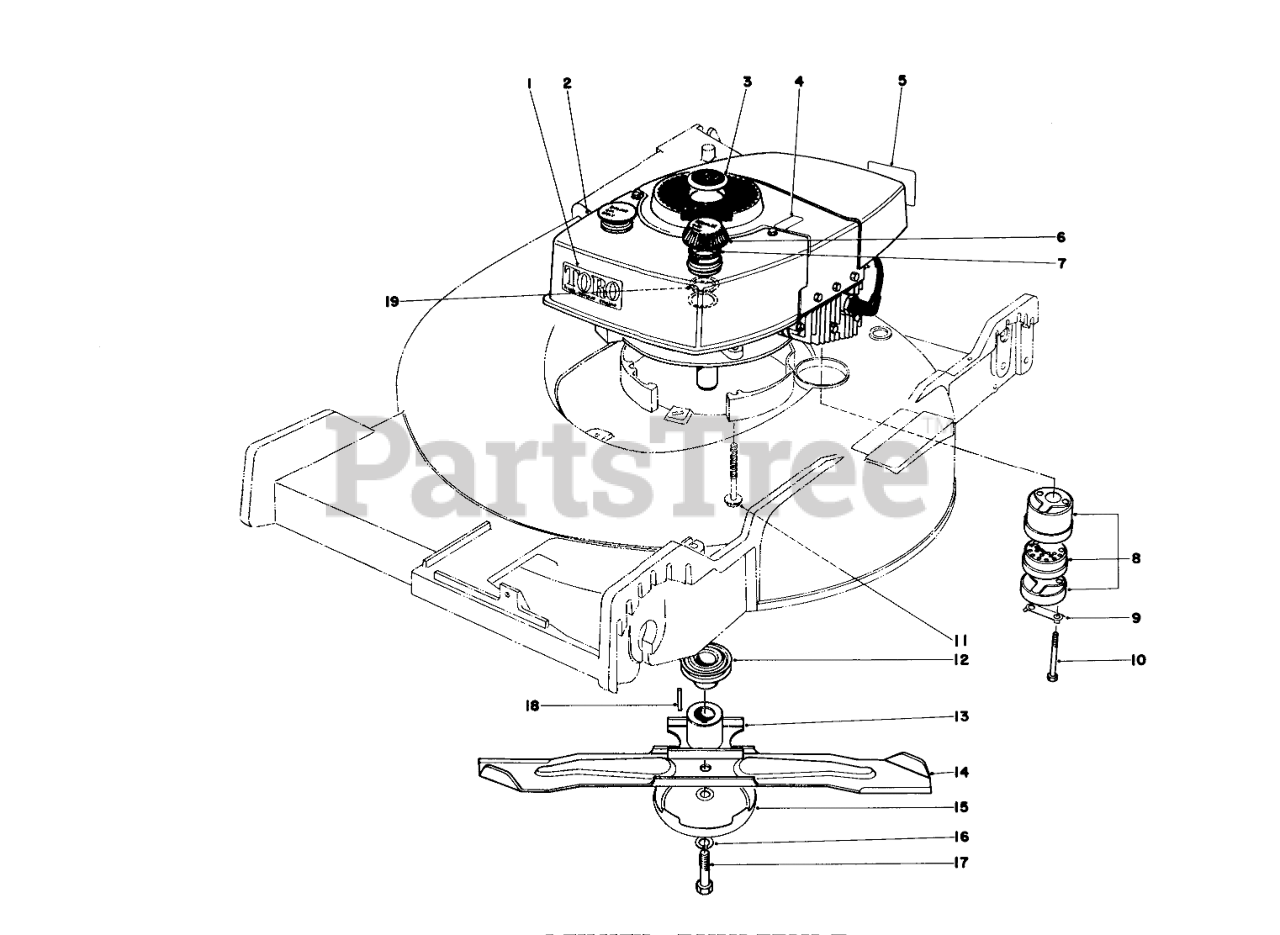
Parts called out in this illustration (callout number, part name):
1	High Torque
2	Engine
3	PLUG BUTTON
4	Decal Lockout
5	Decal Maintenance
6	Gas Cap Assembly (Incl. Ref. #7 & 19)
7	GASKET
8	Muffler Assembly (Incl . Ref. #9 & 10)
9	CLIP - LOCKING
10	SCREW-HH
11	3/8-16 X 2-3/4 CAPSCR
12	DRIVER PULLEY
13	Blade Retainer
14	Blade
15	AntiScalp Cup
16	WASHER-LOCK
17	SCREW-BLADE
18	Key Square
19	GAS CAP BAFFLE
